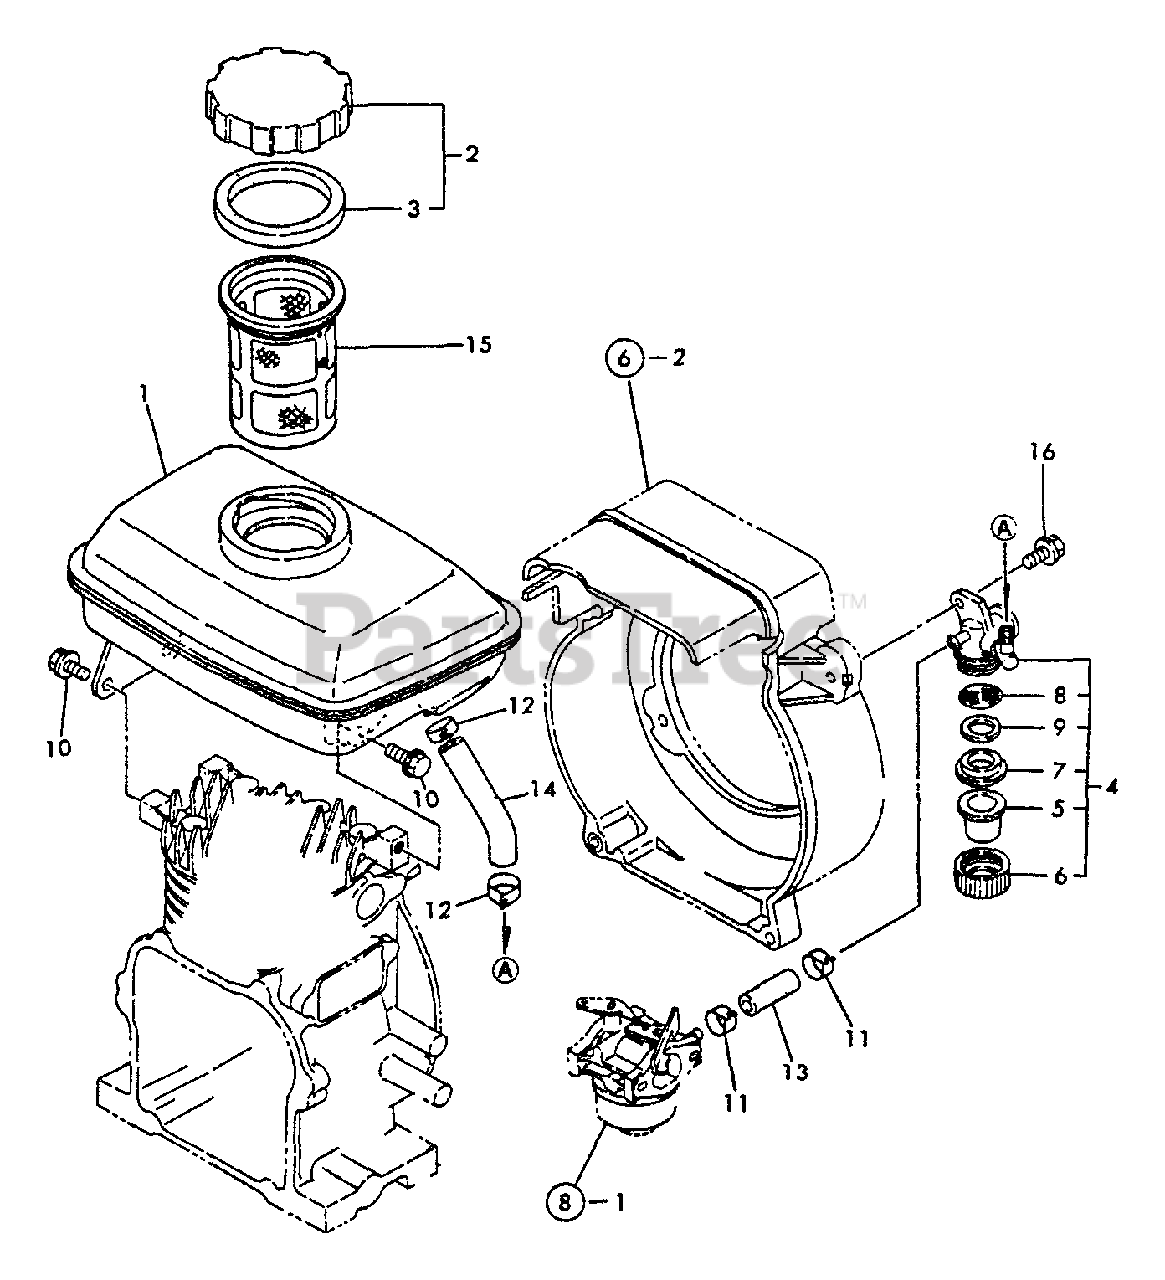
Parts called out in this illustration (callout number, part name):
1	FUEL TANK ASSY
2	CAP ASSY
3	GASKET
4	FUEL COCK ASSY
5	BOWL, STRAINER
6	RETAINER
7	GASKET
8	FILTER, FUEL
9	PLATE
10	BOLT - 6X8 -- PLATED
11	CLAMP, HOSE - 9
12	CLAMP, HOSE
13	PIPE - FUEL
14	PIPE - FUEL
15	STRAINER, FUEL
16	BOLT - 6X12 -- PLATED
